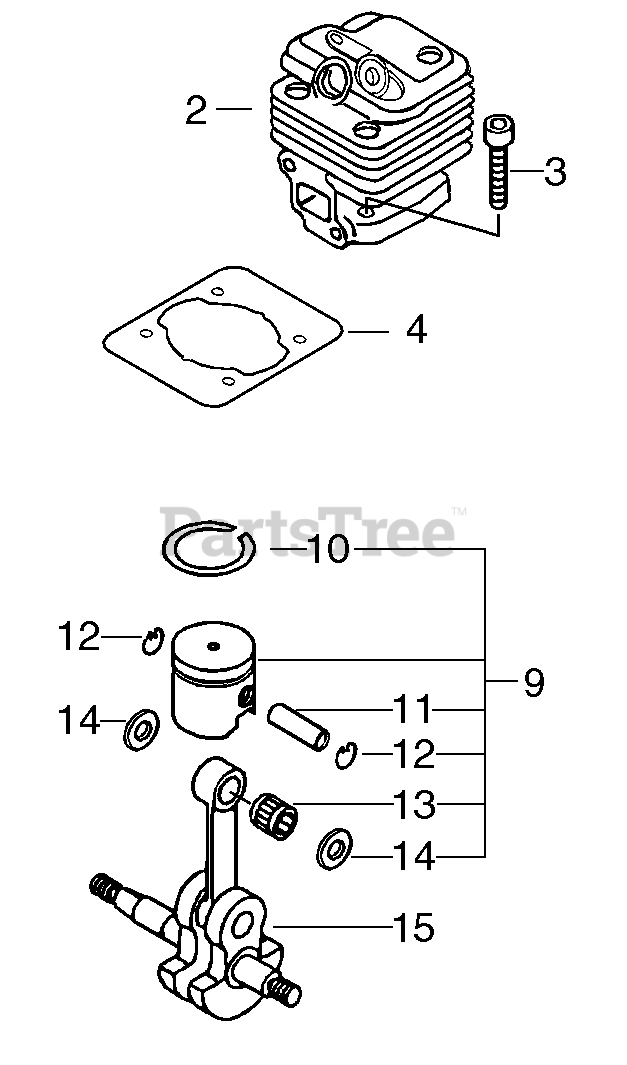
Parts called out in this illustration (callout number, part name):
2	CYLINDER
3	SCREW - 5X20
4	GASKET, CYLINDER
9	PISTON KIT
10	RING, PISTON
11	PIN, PISTON
12	RING, RETAINING - 8
13	BEARING, NEEDLE - 10
14	WASHER - 10
15	CRANKSHAFT ASSY
